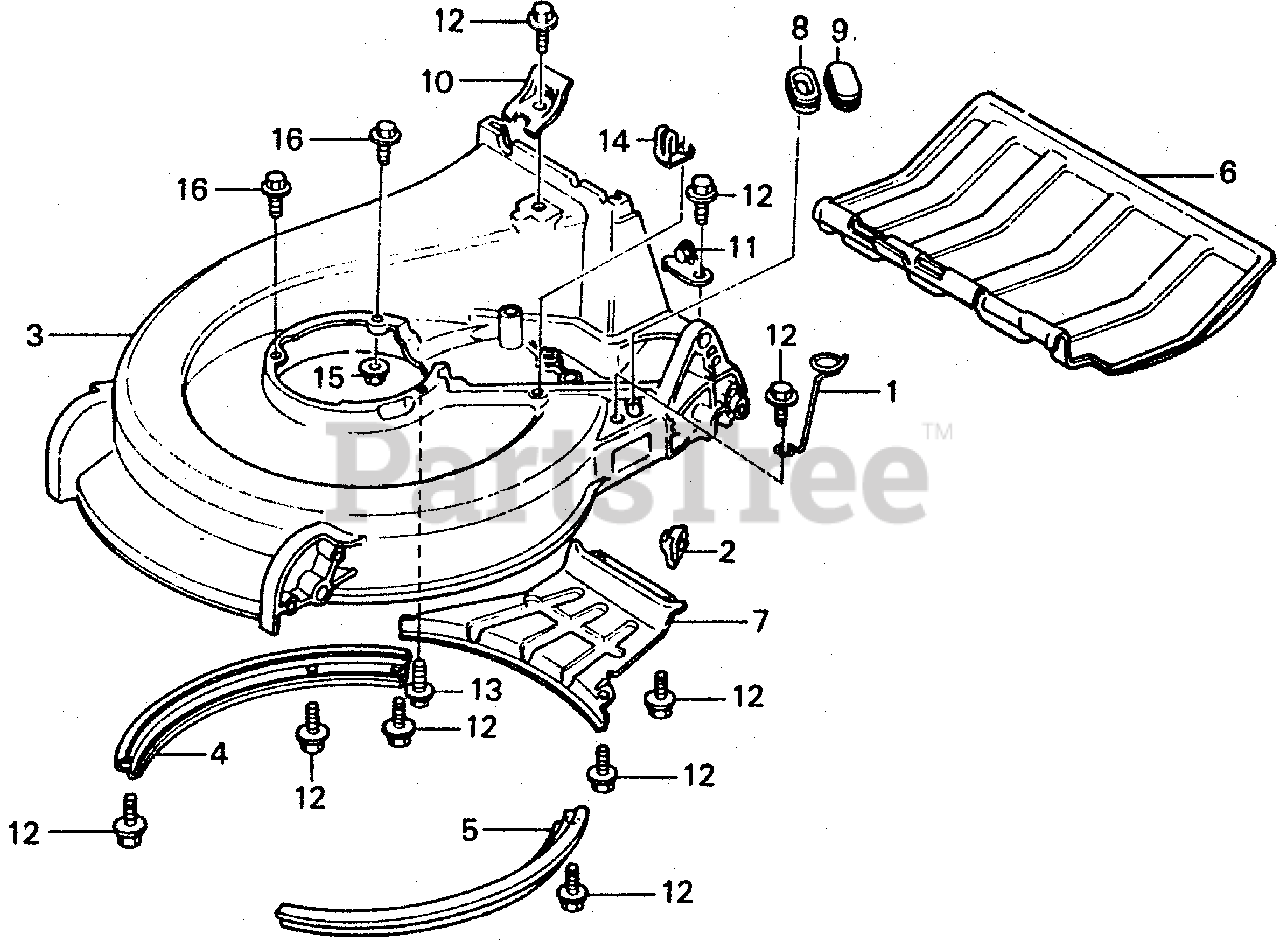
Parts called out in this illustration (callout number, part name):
1	GUIDE, CABLE
2	GROMMET, ROTO-STOP CABLE
3	HOUSING, CUTTER *NH2M* (METALLIC SILVER)
4	GUARD, R. SAFETY
5	GUARD, L. SAFETY
6	SHIELD, SAFETY
7	GUIDE, SCROLL
9	GROMMET, CABLE
10	PLATE, HOOK
11	STAY, PANEL
12	BOLT, FLANGE (6X12) (CT200)
13	BOLT, FLANGE UNF (5/16-24)
14	CLIP, CABLE
15	NUT, FLANGE (8MM)
16	BOLT, FLANGE (8X40)
